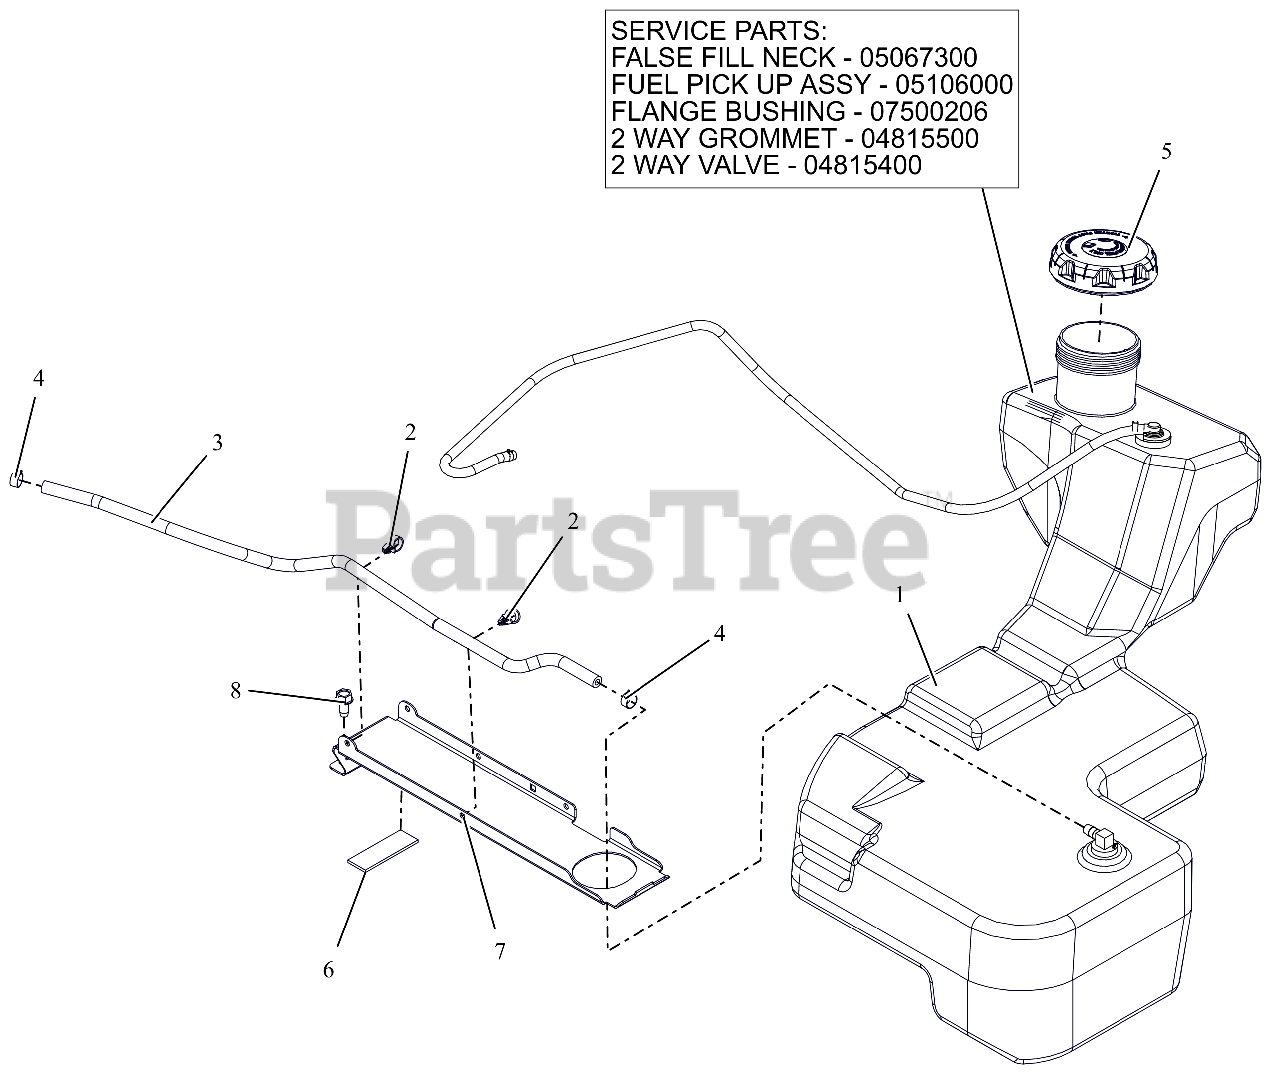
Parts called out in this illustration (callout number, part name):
1	ASSY, FUEL TANK-HD
1	INSERT, FUEL NECK FALSE FILL
1	ASM, HD FUEL PICK-UP
1	BSHG-FLG .375X1.062X.625 NITR
1	GROMMET, 2-WAY
1	VALVE, 2-WAY
2	ROUTING CLIP (1/2" ID)
3	HOSE, .25 LOW-PERM BULK GAS
4	CLAMP, FUEL LINE
5	CAP, FUEL VENTIN AUTOLOCK
6	PAD,RBR 1.0"X3.0" W/ADHESIVE
7	BRKT, FUEL TANK HOLD DOWN
8	SCR,TAP .375-16X.75 HWH TR ZCC
